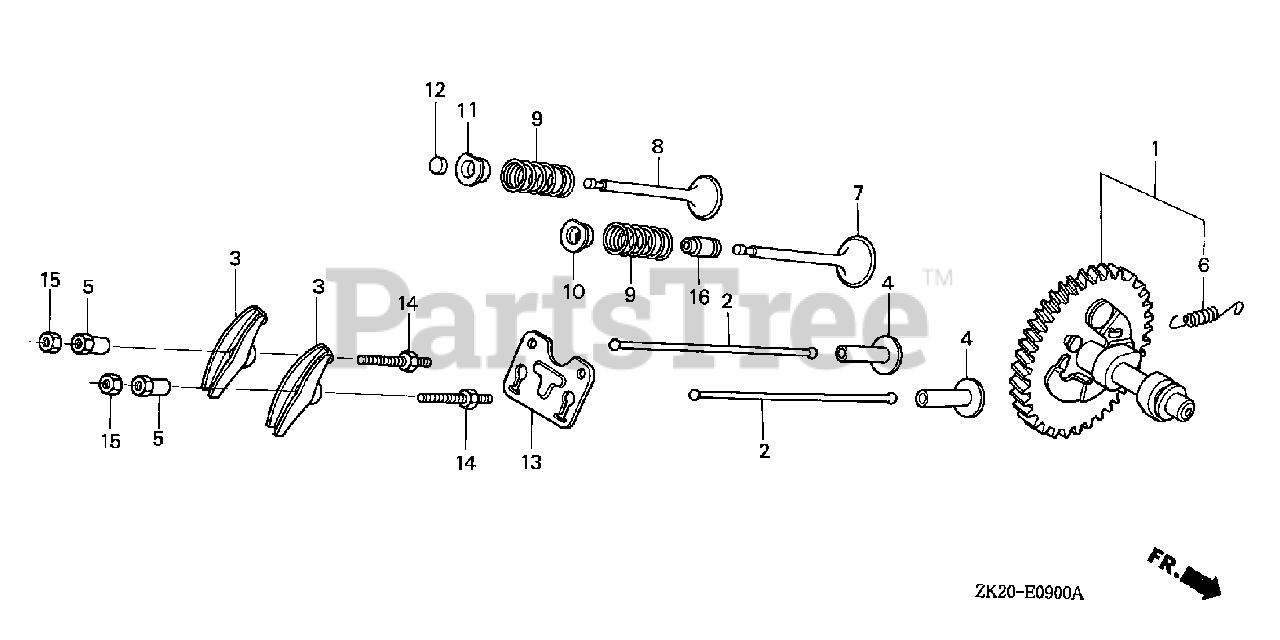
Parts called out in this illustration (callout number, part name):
1	CAMSHAFT ASSY.
2	ROD, PUSH
3	ARM, VALVE ROCKER
4	LIFTER, VALVE
5	PIVOT, ROCKER ARM
6	SPRING, WEIGHT RETURN
7	VALVE, IN.
8	VALVE, EX.
9	SPRING, VALVE
10	RETAINER, IN. VALVE SPRING
11	RETAINER, EX. VALVE SPRING
12	ROTATOR, VALVE
13	PLATE, PUSH ROD GUIDE
14	BOLT, PIVOT (8MM)
15	NUT, PIVOT ADJ.
16	SEAL, VALVE STEM
